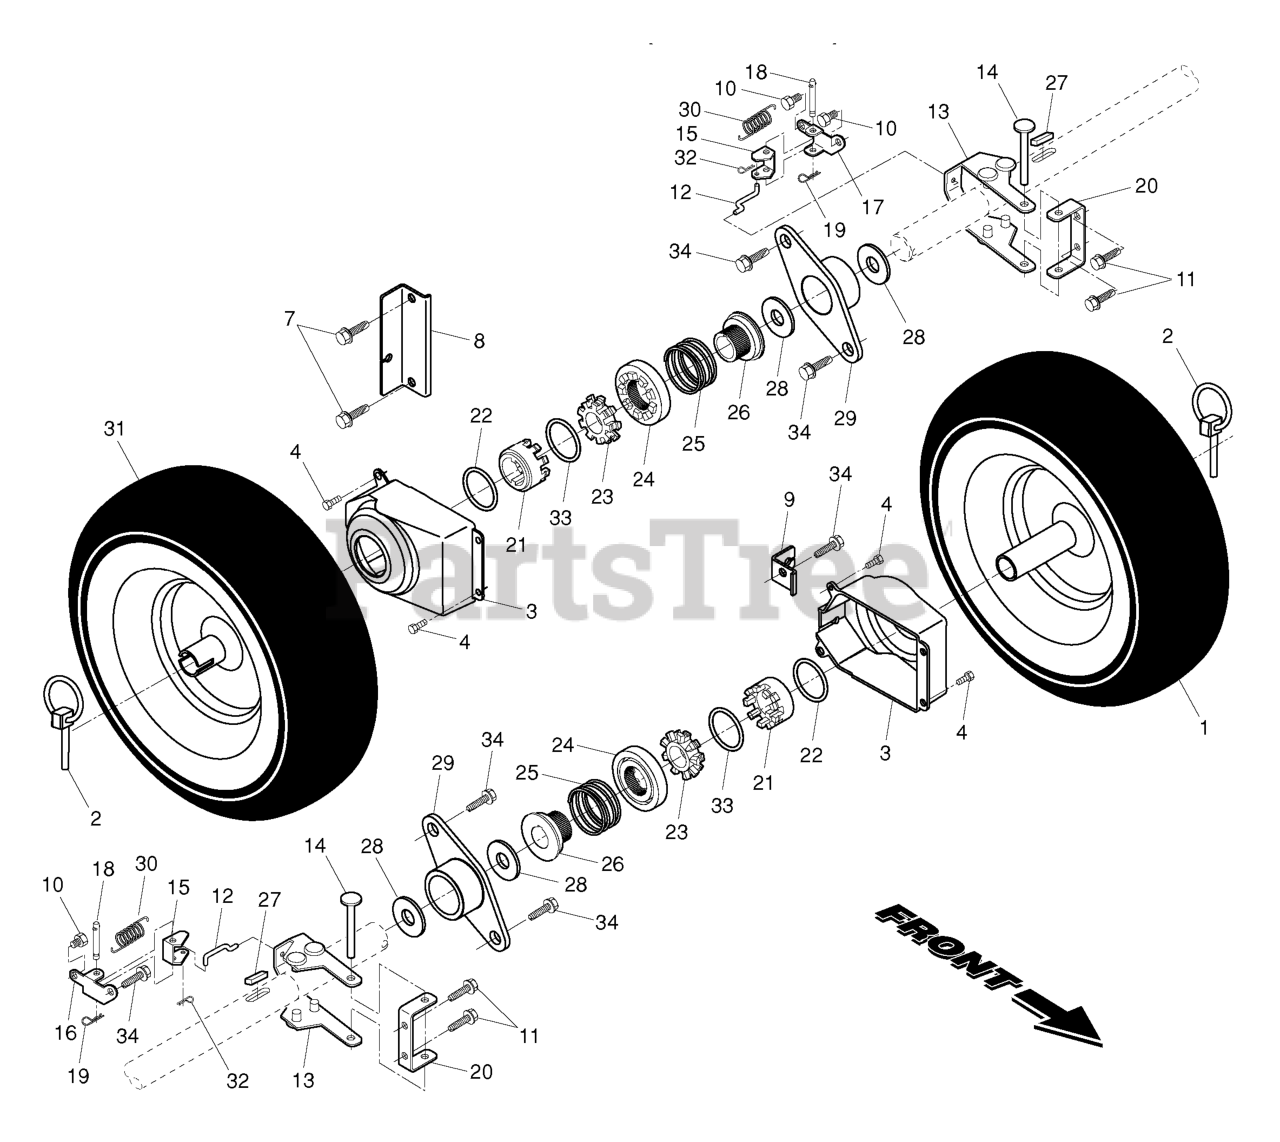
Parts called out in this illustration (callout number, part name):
1	16 X 4.8 LH WHEEL GREY
2	PIN KLIK, 1/4
3	COVER
4	SCREW, HEX HEAD, TAPPING
7	Capscrew, Hex Head, Flanged 3/8-16 x 1
8	BRACKET, STEERING CABLE RH
9	BRACKET, STEERING CABLE LH
10	SCREW 1/4X20
11	Screw, Hex Head 5/16-18 x 1/2
12	LINK.STEER.YOKE
13	YOKE, STEERING
14	PIN, STEERING LEVER
15	BELLCRANK.STEER
16	BRACKET.STEER.PIVOT.LH.YZ
17	BRKT.STEER.PIVOT.RH
18	PIN, STEERING BELLCRANK
19	RETAINER CLIP PM
20	BRACKET.STEER.PNT.BLACK
21	RP.DRIVER WHEEL
22	RING, WIRE RETAINER
23	LOBE WHEEL
24	RP.SLIDE.CLUTCH
25	SPRING, CLUTCH SLIDE
26	RP.LOBE.AXLE
27	KEY, SQUARE 1/4 X .875
28	WASHER TRUST 1"
29	BEARING, AXLE
30	SPRING LATCH
31	16 X 4.8 RH WHEEL
32	RETAINER CLIP
